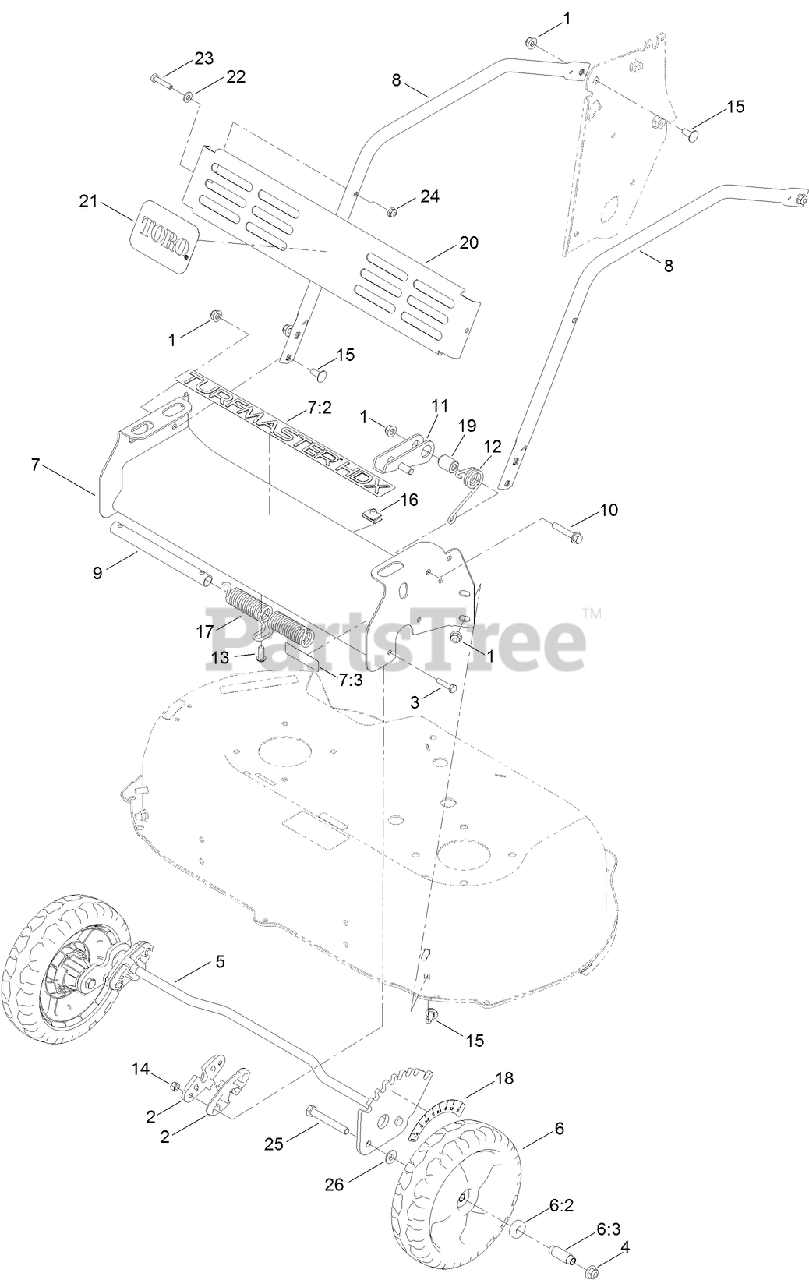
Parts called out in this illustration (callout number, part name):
1	NUT-HF, NI
2	BUSHING-FRONT
3	SCREW-HH
4	NUT-HF, NI
5	FRONT AXLE ASM
6:2	BEARING-BALL
6:3	SPACER
7	FRONT BUMPER ASM
7:3	DECAL-WARNING
9	MANDRELL-SPRING
10	SCREW-HWH
11	LOCK-HEIGHT, ADJ
12	SPRING-TORSION
13	SCREW-HSBH
14	NUT-LOCK, NI
15	SCREW-CARR
16	NUT-U
17	SPRING-TORSION
18	DECAL-HOC, FRONT
19	SPACER
22	WASHER-FLAT
23	SCREW-HH
24	NUT-HF
25	SCREW-HH
26	SPACER-COVER, WHEEL
